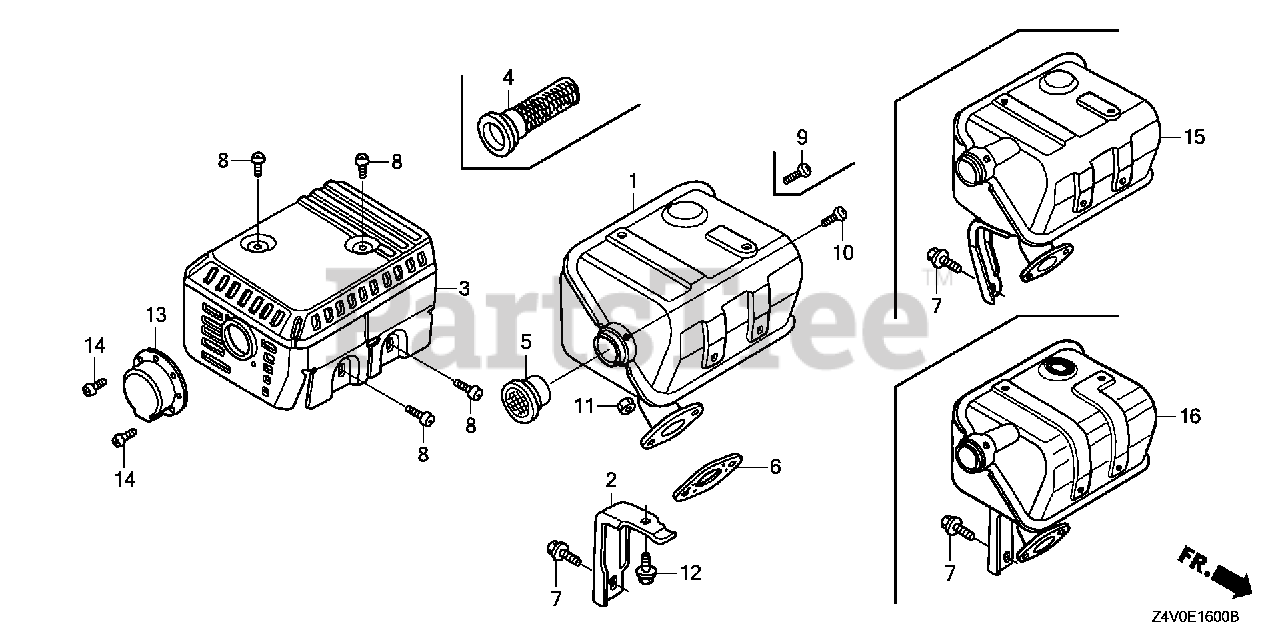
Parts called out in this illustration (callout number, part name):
1	MUFFLER
1	MUFFLER (SILENT)
2	STAY, MUFFLER
3	PROTECTOR, MUFFLER (SILENT)
4	ARRESTER, SPARK
5	NETTING, WIRE FLANGE
6	GASKET, MUFFLER
7	BOLT, FLANGE (6X13) (CT200)
8	SCREW, TAPPING (5X8)
9	SCREW, TAPPING (4X6)
10	SCREW, TAPPING (4X6)
11	NUT, HEX. (8MM)
12	BOLT, FLANGE (6X12)
